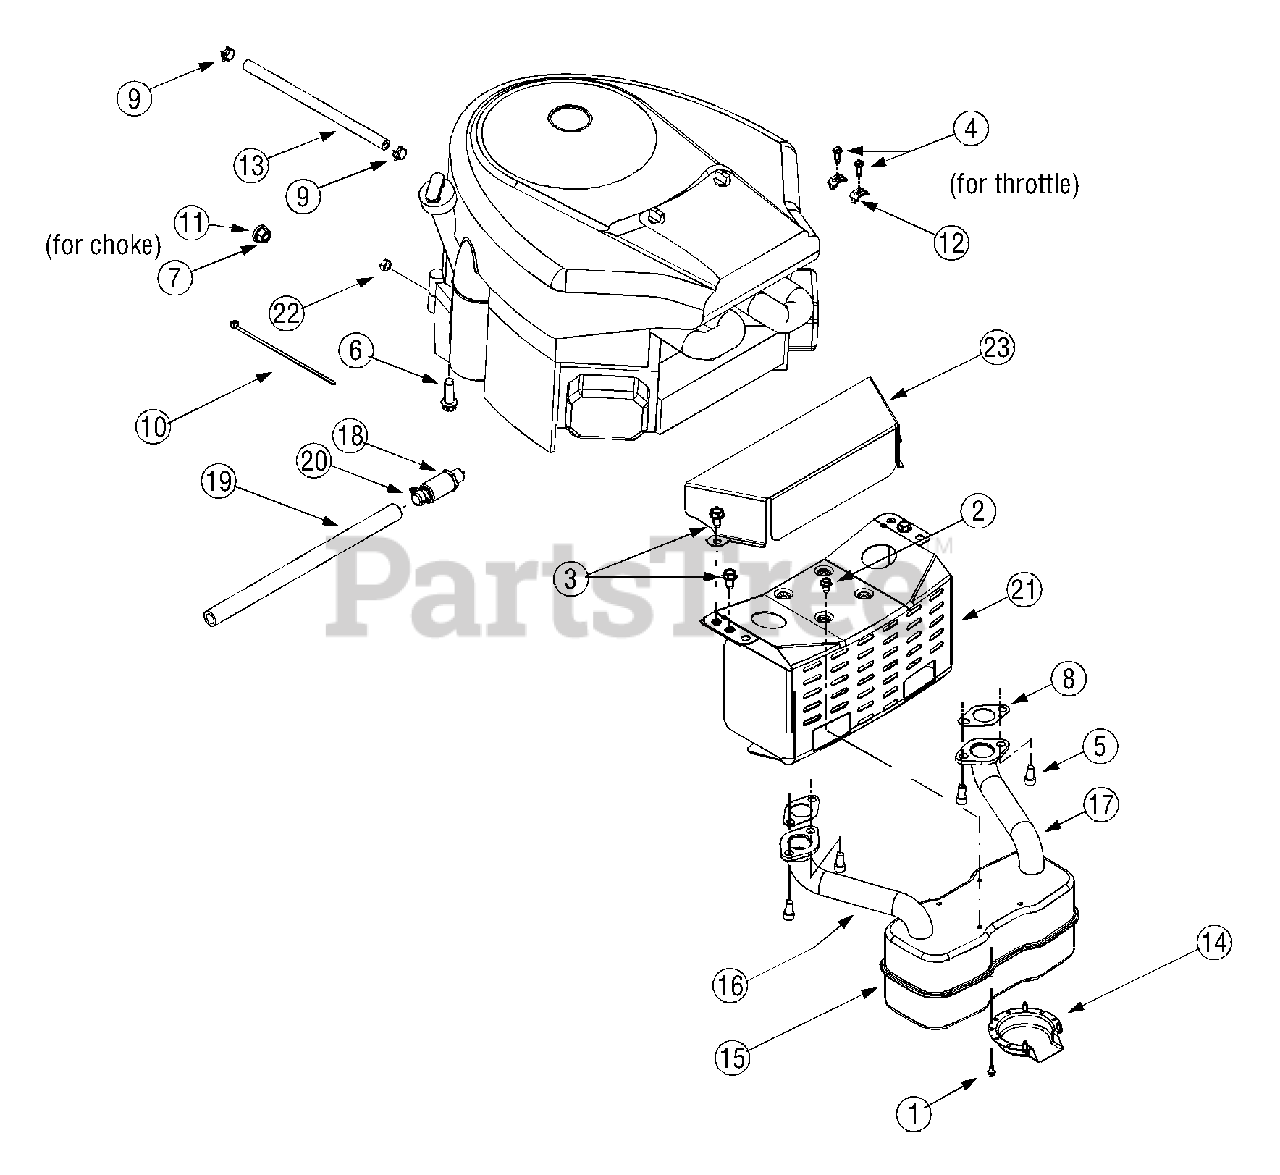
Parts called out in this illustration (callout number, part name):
1	Screw, #8-18 x.50
2	Screw, 1/4-20 x.50
3	Screw, 5/16-18 x.750
4	Screw, #10-32 x.625
5	Socket Cap Screw, 5/16-18 x.625
6	Self-tapping Screw, 3/8-16 x 1.25
7	Flange Lock Nut, 3/8-16
8	Exhaust Gasket
9	Hose Clamp
10	Cable Tie
11	Lock Washer,.406 x.875 x.059
12	Casing Clamp
13	Fuel Line Hose
14	Muffler Deflector
15	Muffler, Twin Inlet
16	RH Exhaust Pipe
17	LH Exhaust Pipe
18	Oil Drain Valve
19	Oil Drain Hose
20	Oil Drain Cap
22	Sems Nut, 1/4-20
23	Heat Shield
